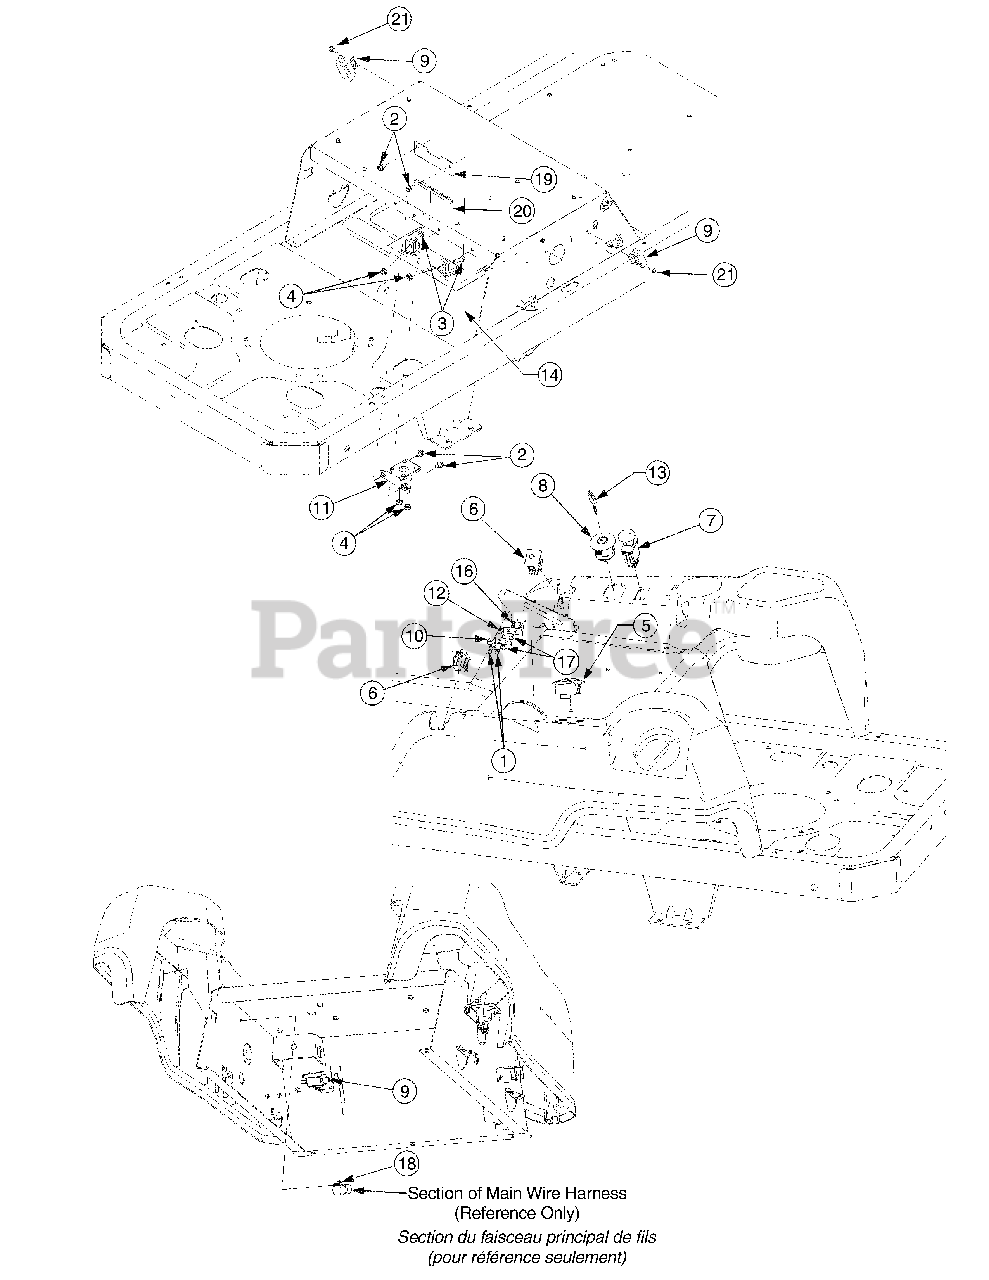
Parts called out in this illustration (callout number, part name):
1	Hex Wash HD AB S-Tapp Scr #8-.50
2	Hex Wash HD Tapp Scr 1/4-20 x .375
3	Hex Cap Bolt 1/4-20 x .75" Lg.
4	Sems Hex Nut 1/4-20
5	Meter, Indicator/Service Monitor
6	Switch, Dbl. Pole - Neutral
7	Switch, PTO
8	Switch, Ignition
9	Switch, Interlock, (NO-NC)
10	Spring Switch
11	Solenoid
12	Seat Spring Switch
14	Battery 245 CCA (Dry)
16	Insulator Plate
17	Insulator Plate
18	Cable Tie 19 x 8.39"
19	Bracket, Battery Holddown
20	Trim Strip 5" Lg.
21	Shoulder Screw #10-32 x .5
